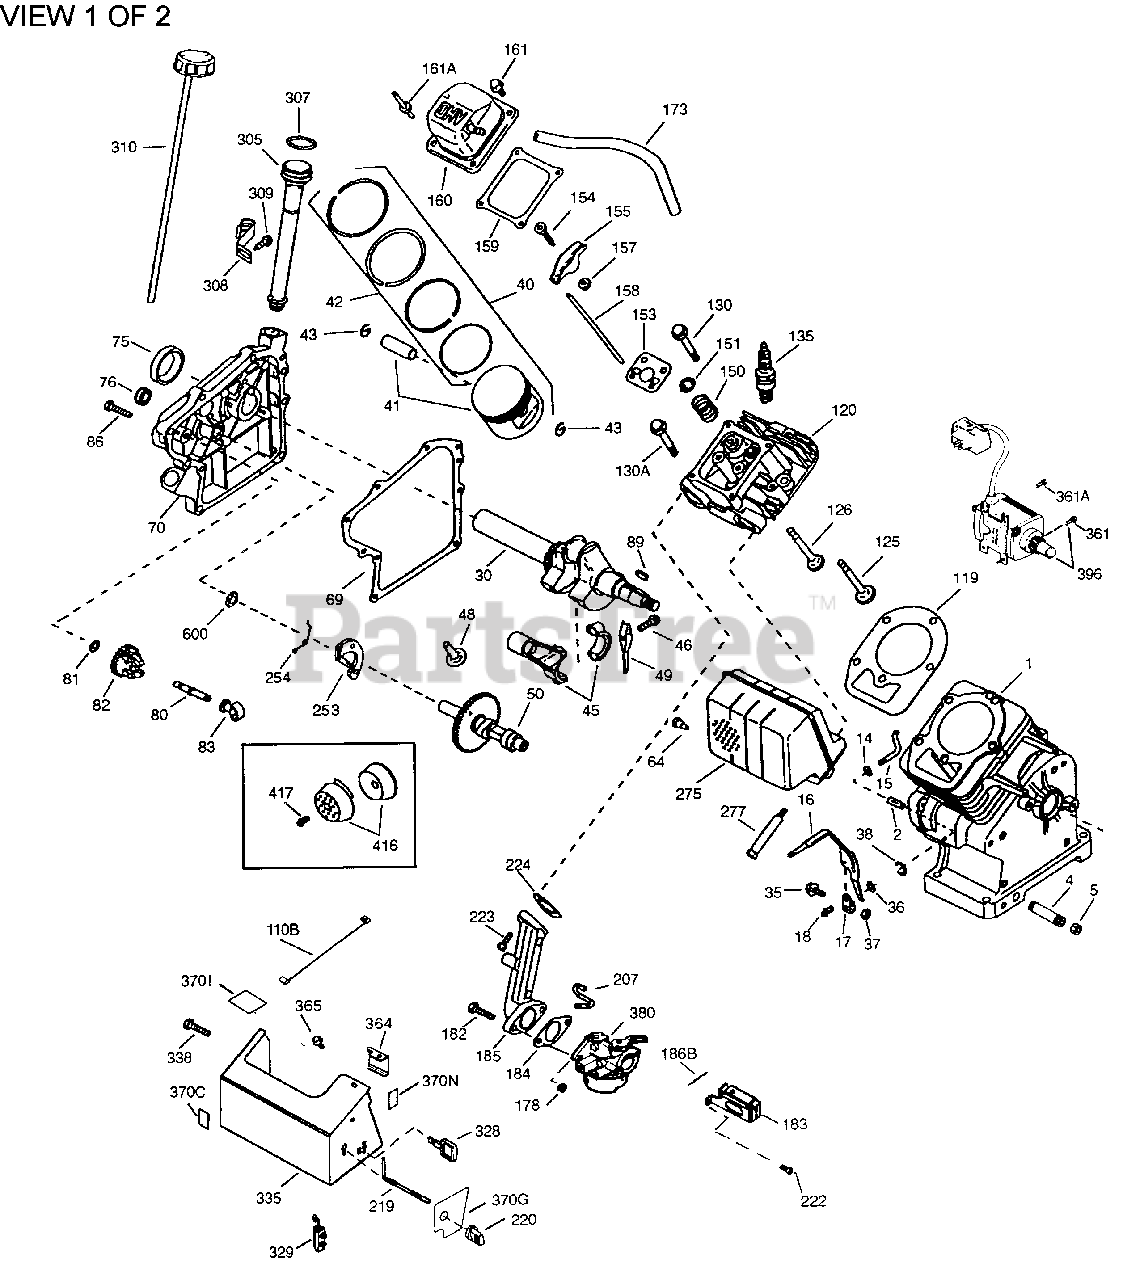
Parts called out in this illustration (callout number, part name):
1	"Cylinder (Incl. 2, 20 & 72)
2	Dowel Pin
4	Oil Drain Extension
5	Extension Cap
14	Flat Washer
15	Governor Rod
16	Governor Lever
17	Governor Lever Clamp
18	Screw, Torx T-15, 8-32 x 3/8"
30	Crankshaft
35	Screw, 10-32 x 3/4"
36	Lock Washer #8
37	Lock Nut, 10-32
38	Retaining Ring
40	Piston, Pin & Ring Set (Std.)
40	Piston, Pin & Ring Set (.010" OS)
41	Piston & Pin Ass'y. (Std.) (Incl. 43)
41	Piston & Pin Ass'y. (.010" OS) Incl. 43
42	Ring Set (Std.)
42	Ring Set (.010" OS)
43	Piston Pin Retaining Ring
45	Connecting Rod Ass'y. (Incl. 46 & 49)
46	Connecting Rod Bolt
48	Valve Lifter
49	Oil Dipper
50	Camshaft (Incl. 253 & 254)
64	Screw, 1/4-20 x 27/32"
69	* Cylinder Cover Gasket
70	Cylinder Cover (Incl. 75 thru 83)
75	Oil Seal
80	Governor Shaft
82	Governor Gear Ass'y. (Incl. 81)
83	Governor Spool
86	Screw, 1/4-20 x 1-1/4"
89	Flywheel Key (also available in Packa ged Part #740007B)
110B	Ground Wire
119	* Cylinder Head Gasket
120	Cylinder Head
125	Exhaust Valve (Std.) (Incl. 151)
125	Exhaust Valve (1/32" OS) (Incl. 151)
126	Exhaust Valve (1/32" OS) (Incl. 151)
126	Intake Valve (Std.) (Incl. 151 & 151A )
130	Screw, 5/16-18 x 1-1/2"
130A	Screw, 5/16-18 x 2-41/64"
135	Resistor Spark Plug (RN4C) also avail able in Packaged Part #740069
150	Valve Spring
151	Valve Spring Cap
153	Push Rod Guide
154	Rocker Arm Stud
155	Rocker Arm
157	Nut, 1/4-28
158	Push Rod
159	* Rocker Arm Cover Gasket
160	Rocker Arm Cover
161	Screw, 1/4-20 x 31/64"
173	Breather Tube
178	Nut, 1/4-20
182	Screw, 1/4-20 x 1"
183	Choke Bracket
184	* Carburetor To Intake Pipe Gasket
185	Intake Pipe
186B	Choke Spring
207	Throttle Link
219	Choke Rod
220	Control Knob
222	Screw, 10-32 x 1/2"
223	Screw, 1/4-20 x 1"
224	* Intake Pipe Gasket
253	Compression Release Weight
254	Compression Release Spring
275	Muffler
277	Screw, 1/4-20 x 2-9/32"
305	Oil Fill Tube
307	"O" Ring
308	Fill Tube Clip
309	Screw, 10-32 x 5/16"
310	Dipstick
328	Ignition Key
329	Terminal
335	Carburetor Cover
338	Screw, 10-32 x 1/2"
342A	Screw, 1/4-20 x 5/8"
355	Starter Handle (Mitten Grip) also ava ilable in Packaged Part #740053B
361	Screw, 1/4-20 x 5/8"
364	Carburetor Cover Bracket
365	Screw, 10-32 x 1/2"
370C	Primer Decal
370G	Instruction Decal
370I	Warning Decal
370P	Heat Warning Decal
380	Carburetor (Incl. 184)
396	Electric Starter Motor (110 Volt)
416	Spark Arrestor Kit (Incl. 417) Option al
417	Screw, 8-32 x 3/8"
999	Winter Maintenance Kit incl. 5W30 Oil , Spark Plug, Key & Ultra-Fresh
999	Winter Maintenance Kit (incl. 0W30 Sy nthetic Oil, Spark Plug, Key & Ultra- Fresh)
